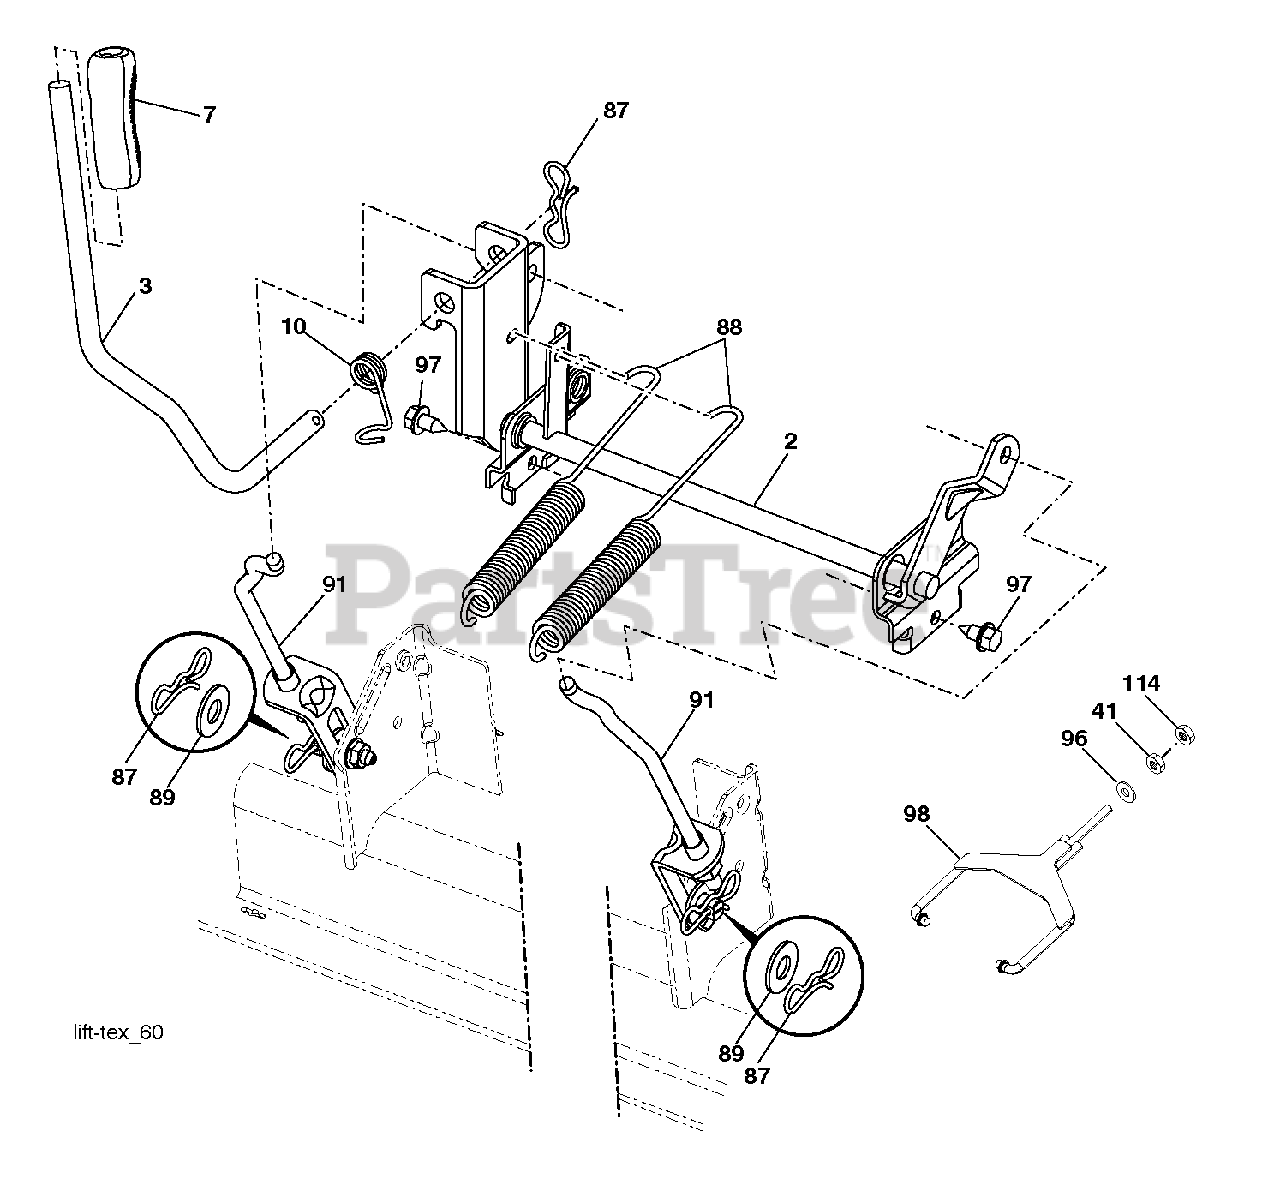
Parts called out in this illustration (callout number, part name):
2	SHAFT.ASM.CROSS.LIFT
3	LEVER.LIFT.HANDLE.GT
7	GRIP.HANDLE.LIFT.PVC.BLACK
10	SPRING.TORSION.LIFT.HANDLE
41	NUT, LIFT LINK 7/16-20
87	PIN.COTTER.7/16.BOW TI.
88	SPRING.LIFT.ASSIST.GT2
89	WASHER.CLEAR.ZINC
91	LINK.ASM.LIFT.54"TG
96	BUSHING SPHERICAL SUSP. FRONT
97	SCREW, 3/8-16X3/4
98	DECK ATTACHMENT FRONT LINK WEL
114	NUT **
